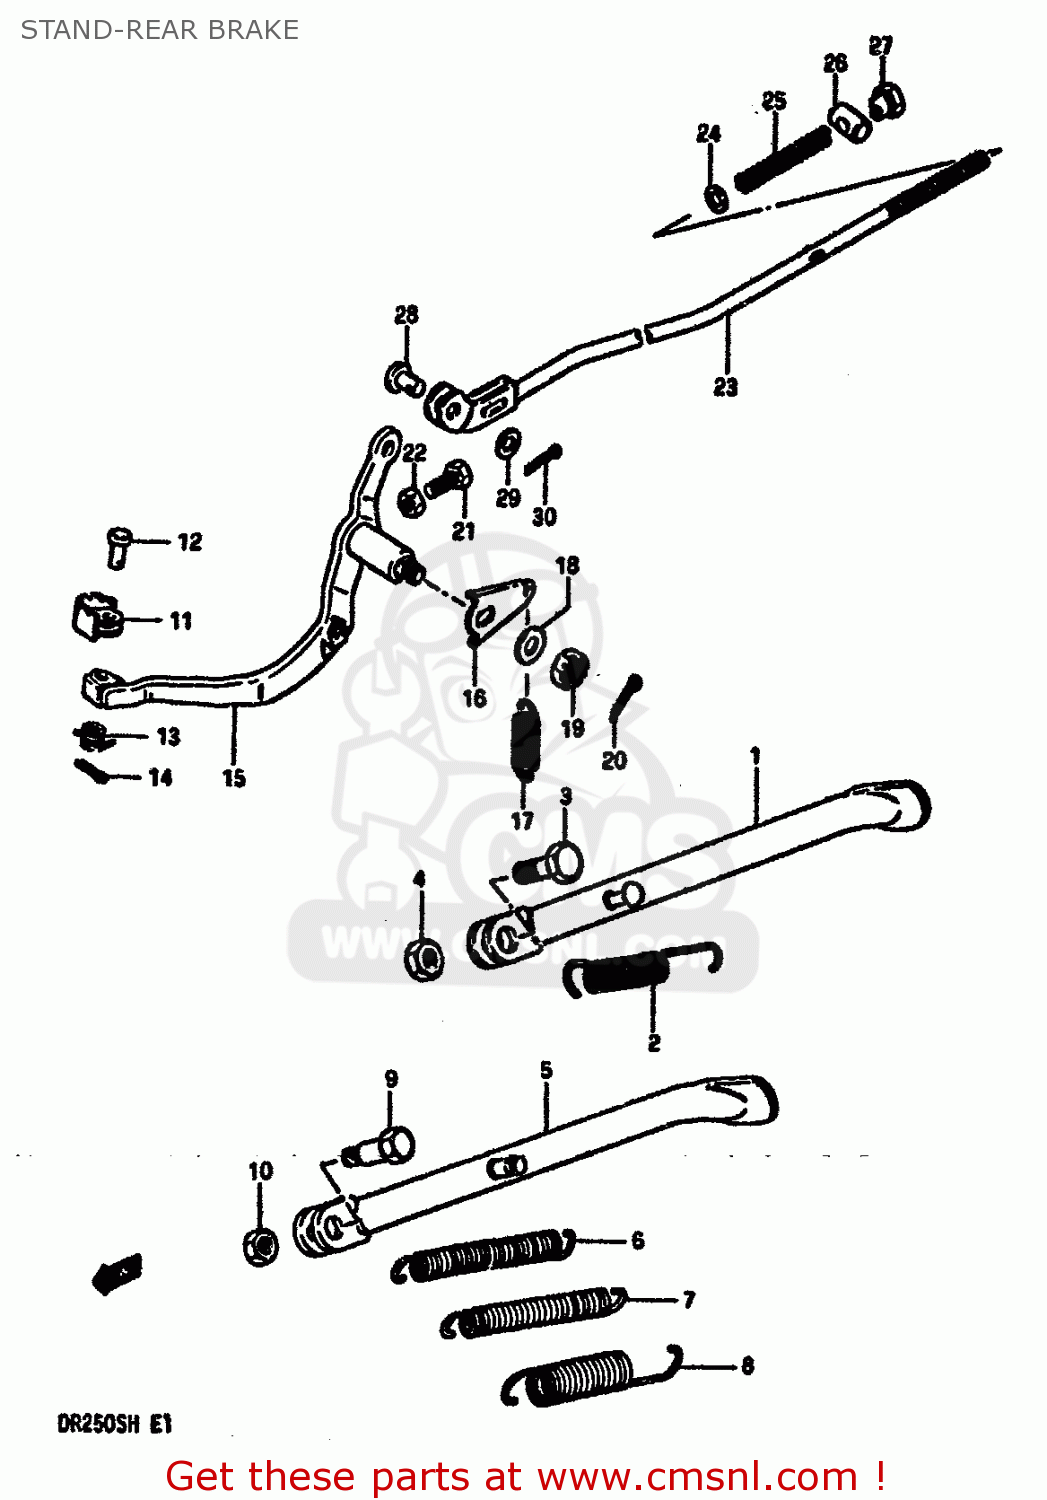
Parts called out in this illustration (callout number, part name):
1	STAND,SIDE
2	SPRING
3	BOLT(10X30)
4	NUT
5	STAND,PROP (BLUE)
6	SPRING
7	SPRING
8	SPRING, OUTER
9	BOLT L:30
10	NUT
11	PEDAL,BRAKE
12	PIN
13	SPRING
14	PIN
15	ARM,BRAKE PEDAL ROD
16	ARM,BRAKE RETURN SPRING
17	SPRING
18	WASHER
19	NUT 8MM
20	PIN 20X20
21	BOLT(6X23)
22	NUT
23	ROD ASSY REAR BRAKE
24	WASHER
25	SPRING
26	PIN(11X18)
27	NUT (6MM)
28	PIN
29	WASHER
30	PIN 20X20
